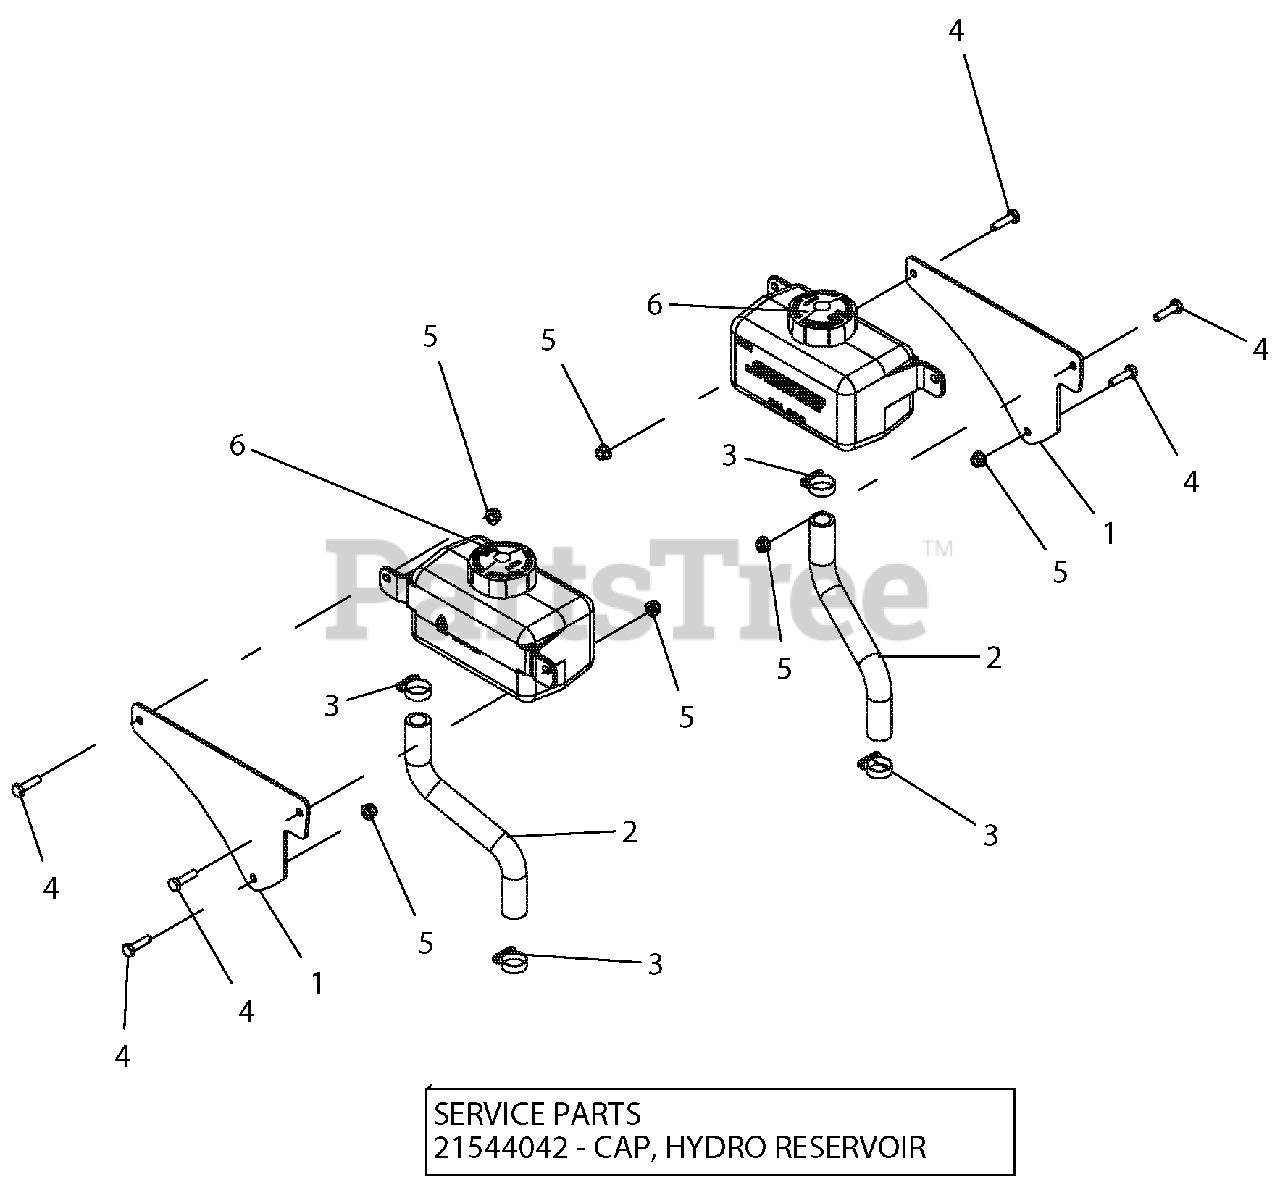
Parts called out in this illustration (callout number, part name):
1	PLATE, HYDRO OVERFLOW TANK MTG
2	HOSE, HYDRO OVERFLOW
3	CLAMP, .88 DIA HOSE
4	BLT-HEX .25-20X1.00 GR5 YWZC
5	NUT-LK-NYL-FLG .25-20 YWZC
6	TANK, HYD 1000ML
